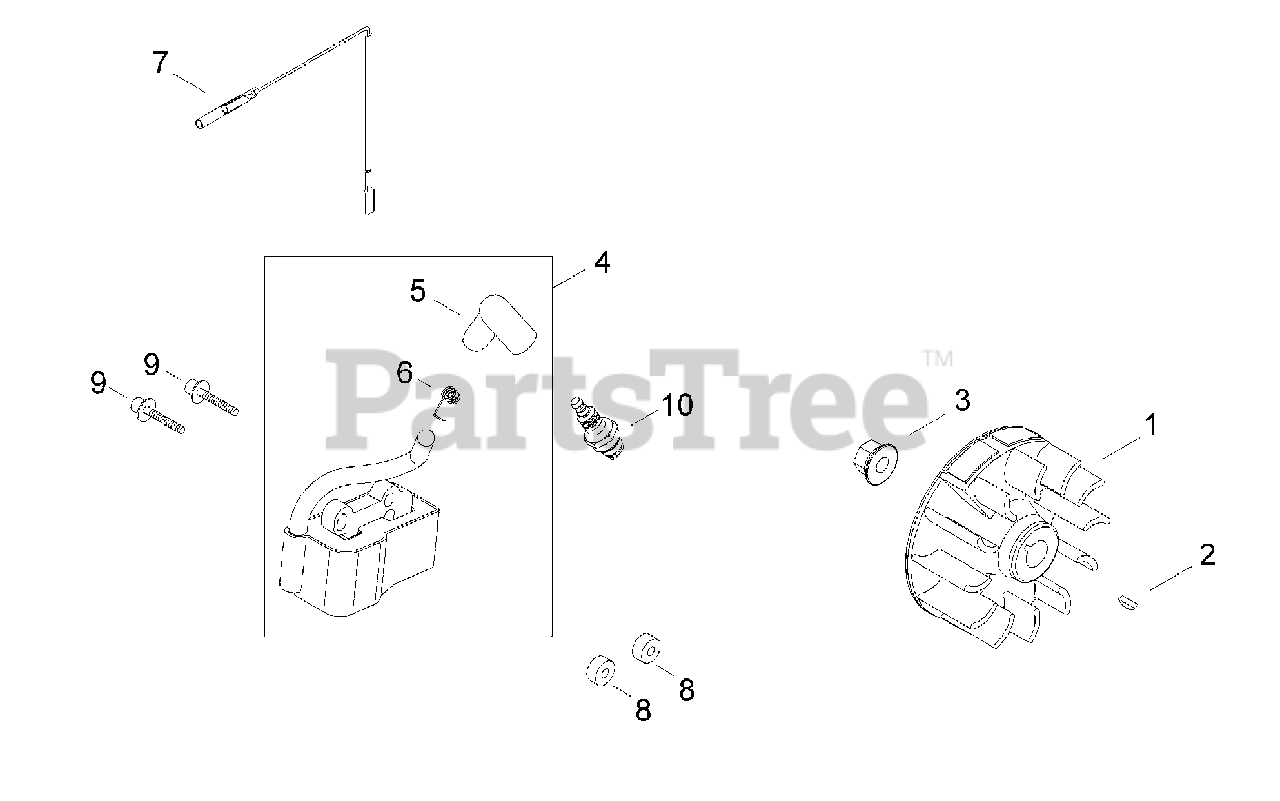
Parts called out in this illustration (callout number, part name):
1	FLYWHEEL
2	KEY - 3X10
3	NUT - 8
4	IGNITION COIL ASSY
5	CAP, SPARK PLUG
6	TERMINAL, SPARK PLUG CAP
7	LEAD - IGNITION
8	INSULATOR
9	SCREW - 4X26
10	SPARK PLUG -- CMR-5H
